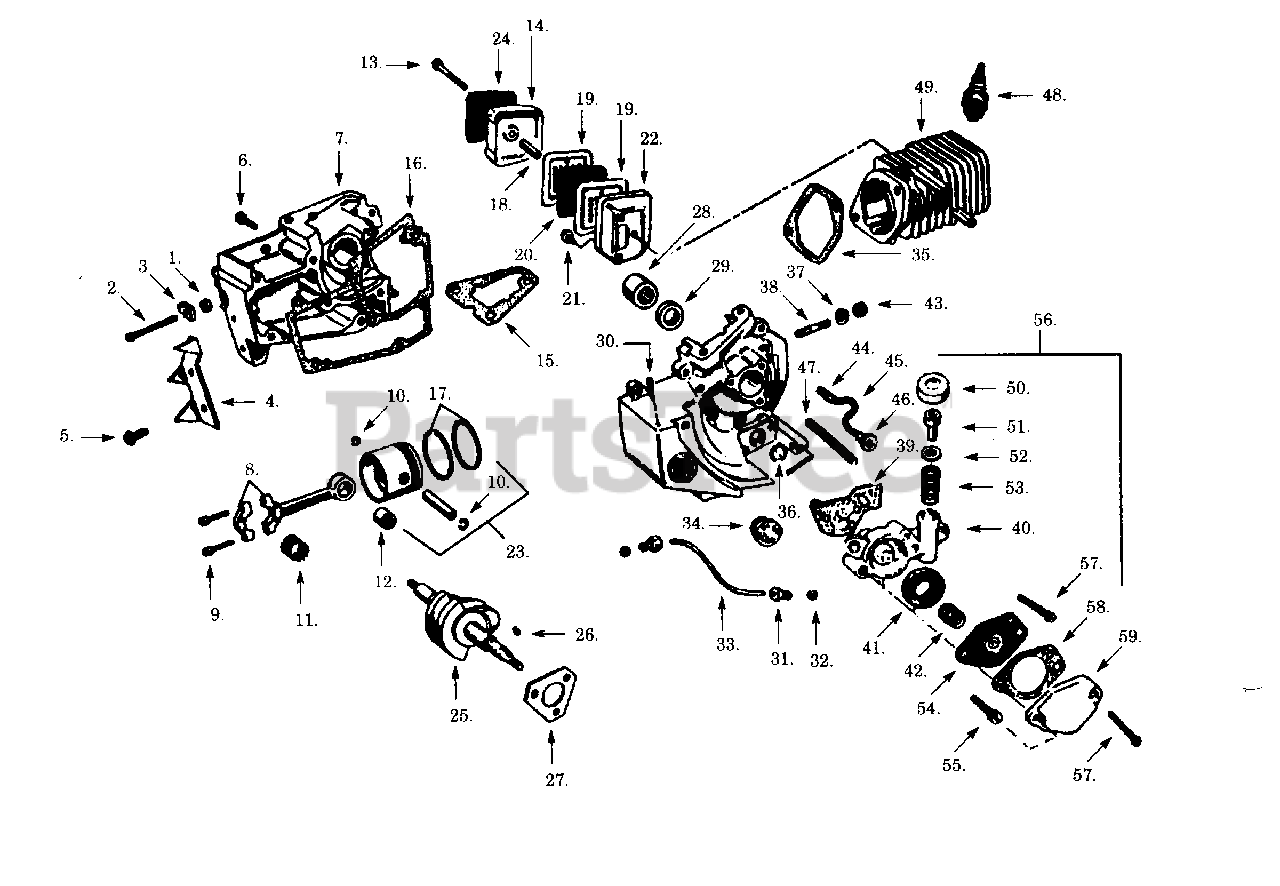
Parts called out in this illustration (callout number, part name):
2	Screw
3	Bar Adjusting Pin
4	Spur (Optional)
7	Crankcase Ass'y.
8	Connecting Rod Ass'y.
10	Piston Pin Retainer
11	Crankpin Rollers
12	Piston Pin Bearing
14	Muffler Cover
15	Gasket
16	Crankcase Gasket
17	Piston Rings
18	Muffler Spacer
19	Muffler Baffle
20	Muffler Screen
22	Muffler Body
23	Piston Ass'y.
24	Muffler Shield
25	Crankshaft
26	Flywheel Key
27	Crankcase Washer
29	Seal
30	Oil Vent Pin
31	Discharge Line Fit ting
32	Ferrule 1/8" Tubing
33	Discharge Line-Oil Pump (Bulk 8115)
34	Oil Cap
35	Cylinder Gasket
37	Cylinder Washer
38	Cylinder Studs
39	Oil Pump Body Gasket
40	Oil Pump Body
41	Pump Body Filter
42	Diaphragm Spring
44	Oil Pick-up Weight
45	Oil Line (Bulk 8132)
46	Oil Pump Intake Valve
47	Oil Line Protector Spring
48	Spark Plug
49	Cylinder
50	Oil Pump Cap
51	Oil Pump Plunger
52	Quad Ring Plunger
53	Oil Pump Spring
54	Diaphragm Ass'y.
56	Pump Ass'y.
58	Pump Body Cover Gasket
59	Oil Pump Ass'y. Cover
